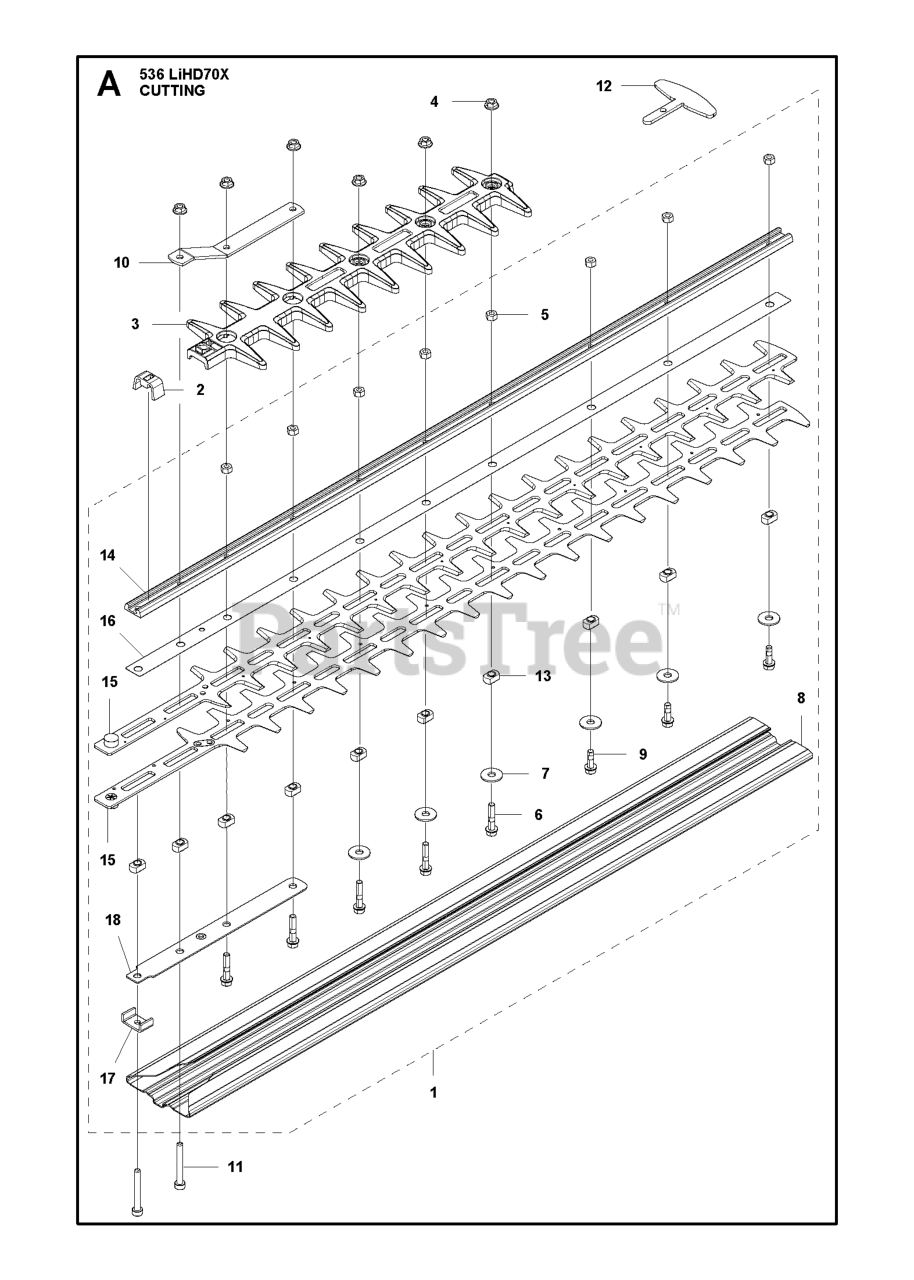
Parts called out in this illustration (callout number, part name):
3	PROTECTION ASSY BLADE
4	HEXAGON NUT FLANGE M5 8 ZN/FE
5	HEXAGON NUT ISO 4032-M5-10
6	SCREW IHSCFM M5X25 10.9 ZN/FE
7	WASHER 6,4X18X1,5
8	TRANSPORT GUARD CUTTING DECK H
9	SCREW IHSCFM M5X16 10.9 ZN/FE
10	SUPPORT CUTTING DECK
11	SCREW IHSCT EN ISO 4762 / DIN
12	PROTECTION BLADE TIP
13	SPACER HEDGE TRIMMER
14	BAR CUTTING DECK LIHD70
16	WEAR PLATE HD70
17	BRACKET
18	BAR
